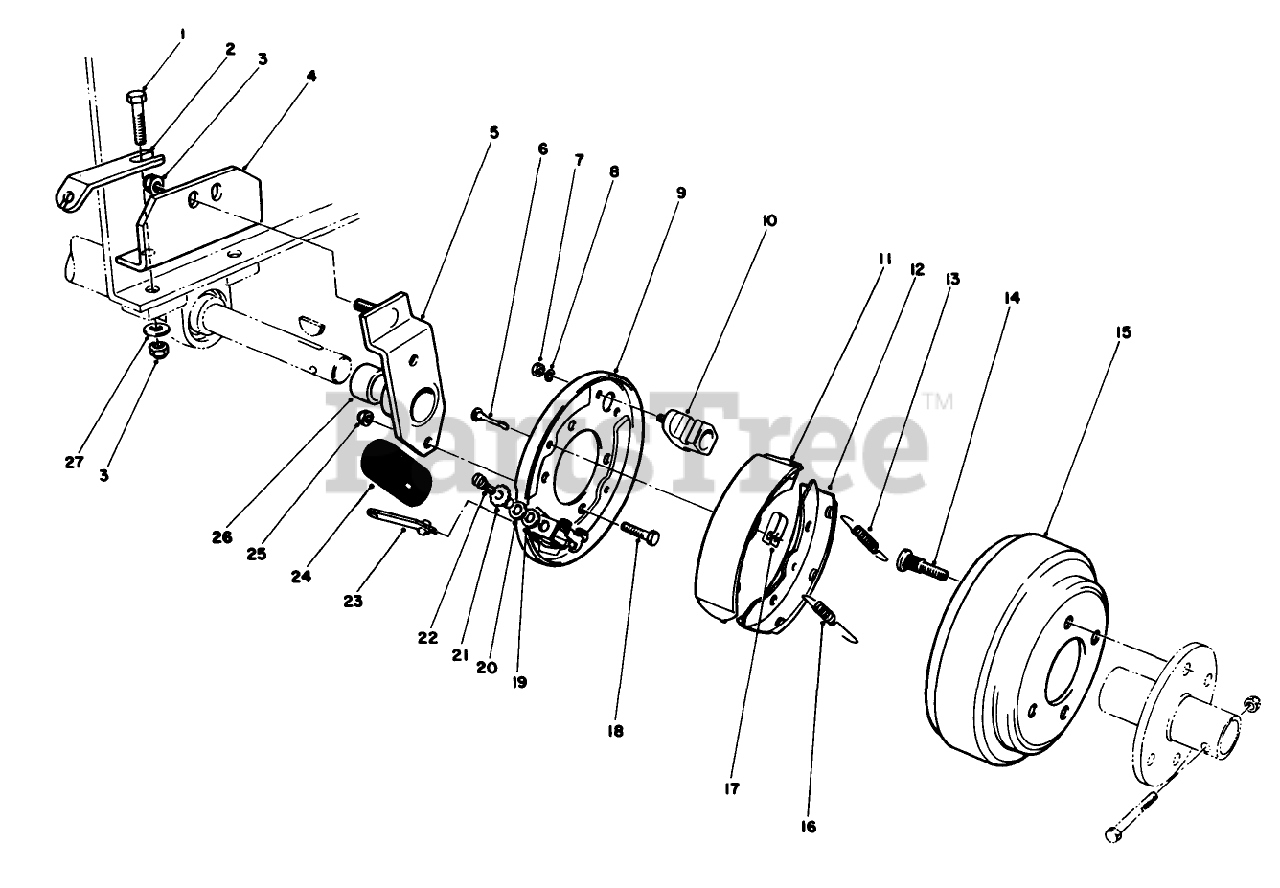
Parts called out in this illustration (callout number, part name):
1	NUT-HEX
1	SCREW-HH
2	WASHER-LOCK, INT
2	LOWER CABLE BRKT B
3	BRACKET F/W
3	NUT-LOCK, NI
4	Hour Meter (Incl. Ref. #1-3)
4	MT BRKT B
5	HR.METER BRKT. R
5	Brake Bracket Assembly (Incl. Ref. #26)
6	TENSION PIN
8	SPRING WASHER
9	Plate Assembly-LH
10	ADJUSTER
12	TRAILING SHOE
13	BRAKE SPRING
14	WHEEL BOLT
16	BRAKE SPRING
17	SHOE CLAMP SPRING
18	SCREW-HH
19	WASHER
20	THRUST WASHER
21	ADJ NUT
22	ADJ BOLT
23	LH LEVER ASM
24	DUST COVER
25	NUT-LOCK, NI
26	BUSHING #AA-1232
27	WASHER-FLAT
